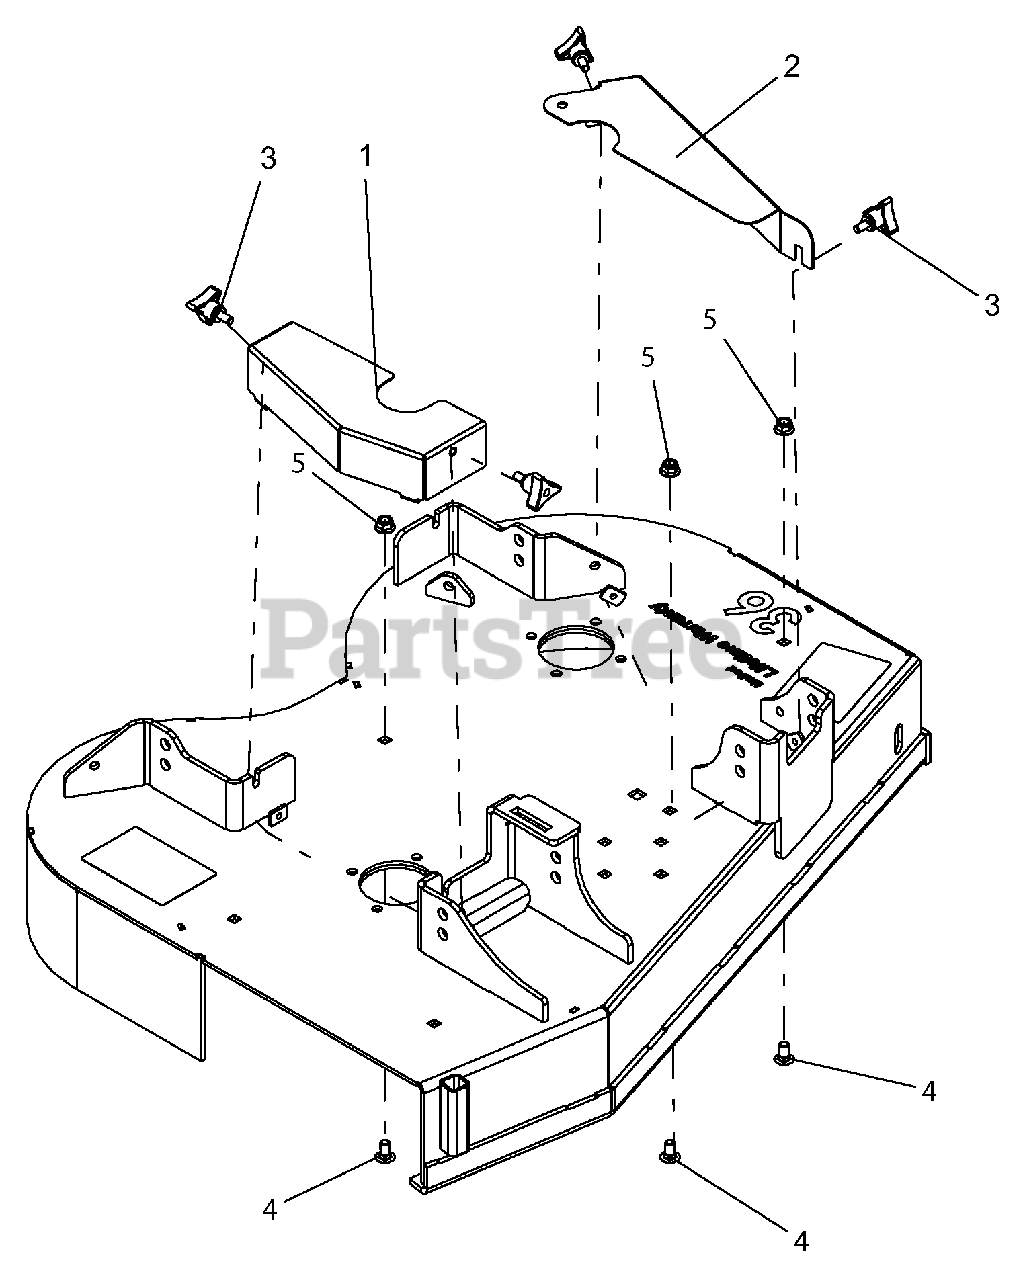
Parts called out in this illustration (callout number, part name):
1	WLDMT, GUARD RH SPINDLE
2	GUARD, LH SPINDLE
3	KNOB, WING STUD .312-18X.75
4	BLT-RDHDSQNK .38-16X.75 G5 YWZC
5	NUT-LK-NYL-FLG .38-16 YWZC
